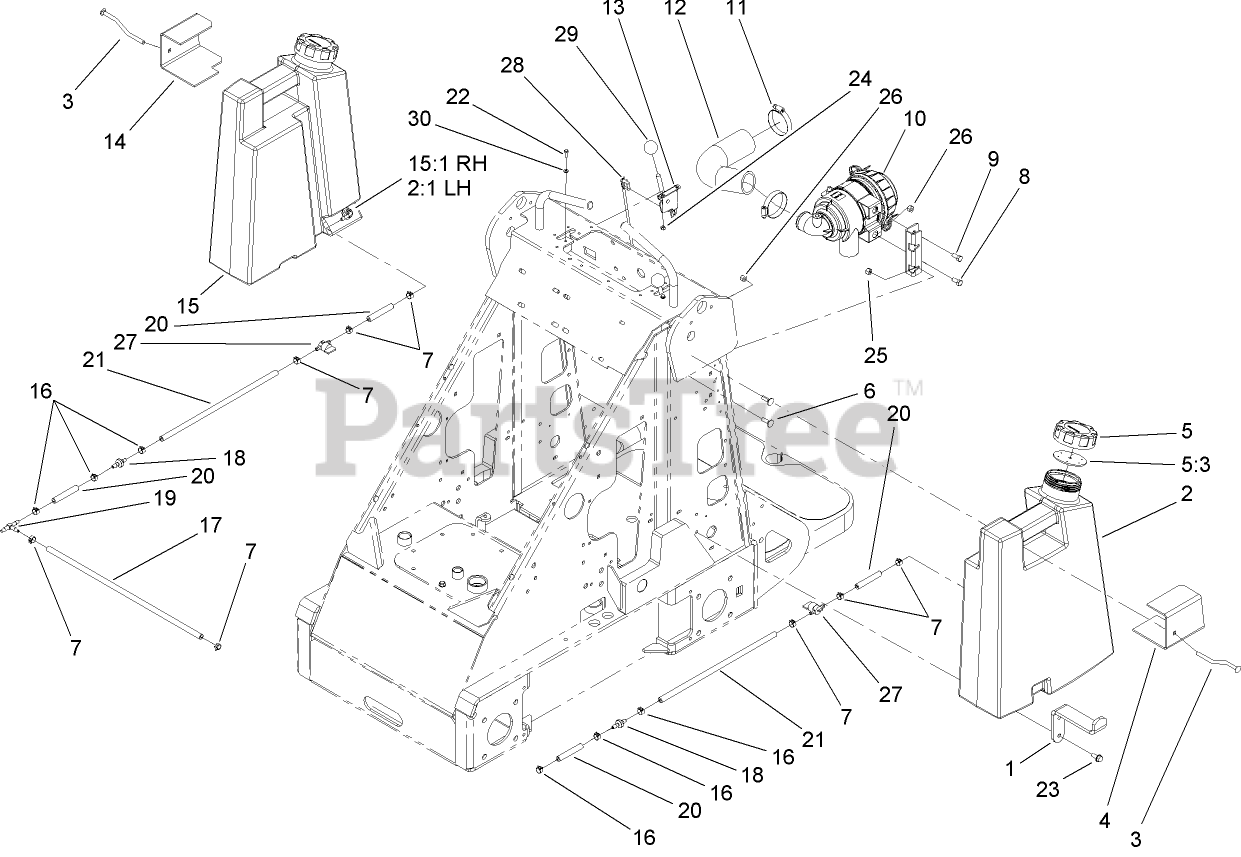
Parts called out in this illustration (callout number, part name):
1	MOUNT-BOTTOM, TANK
2	LH Fuel Tank ASM
2:1	FITTING-FUEL, BULKHEAD
3	BOLT-MOUNT
4	PLATE-MOUNT, LEFT
5	CAP-FUEL, GAS
5:3	GASKET-VENTED
6	BOLT-CARR
7	CLAMP-HOSE
8	SCREW-HH
9	MOUNT-CLEANER, AIR
10	AIR CLEANER ASM
11	CLAMP-HOSE
12	HOSE-AIR
13	LEVER-CONTROL
14	PLATE-MOUNT
15	RH Fuel Tank ASM
15:1	FITTING-FUEL, BULKHEAD
16	CLAMP-HOSE
17	HOSE-FUEL
18	VALVE-CHECK, FUEL
19	FITTING-TEE, BARBED
20	HOSE-FUEL
21	HOSE-FUEL
23	SCREW-HWHTF
24	NUT-KEPS
25	NUT-HF
26	NUT-LOCK, NI
27	VALVE-FUEL
28	CABLE-CONTROL
30	WASHER-FLAT
